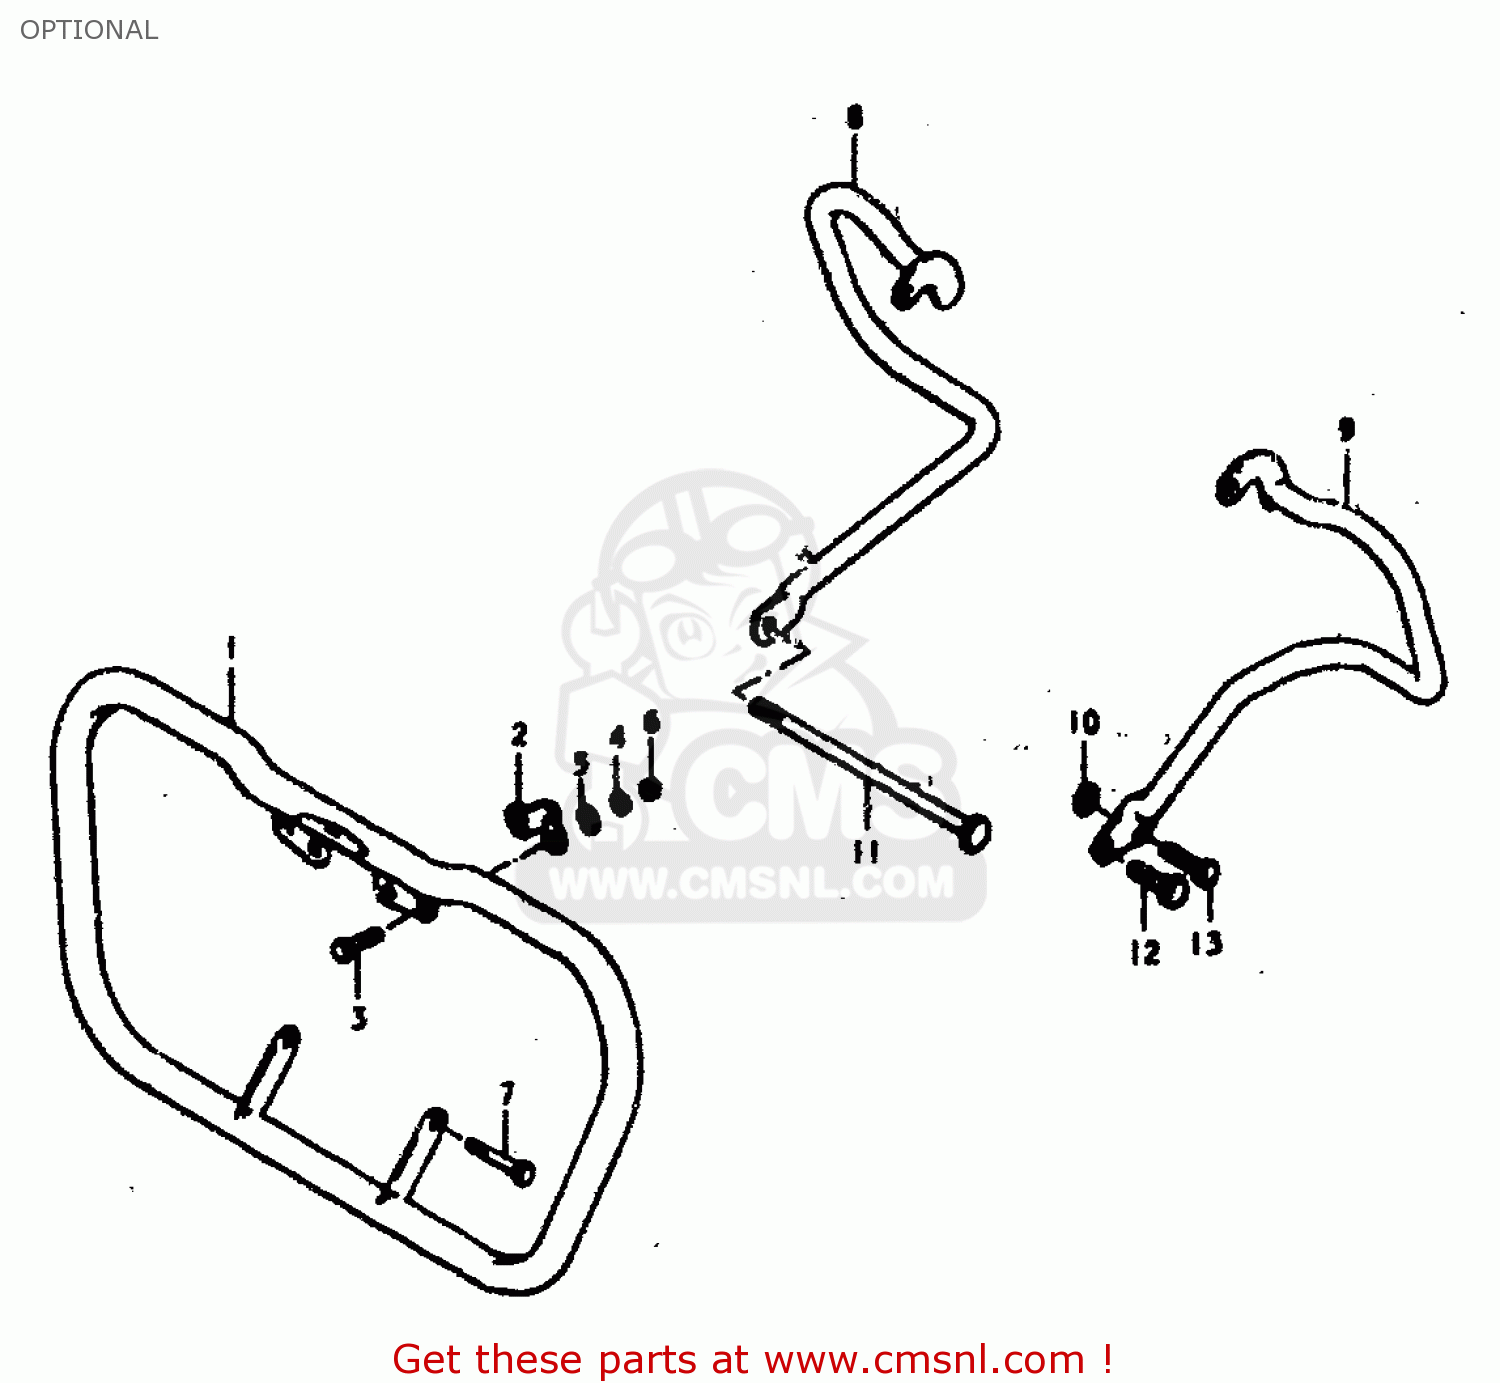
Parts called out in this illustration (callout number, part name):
1	BUMPER,FRONT
2	PLATE, UPPER
3	BOLT
4	LOCK WASHER
5	WASHER
6	NUT
7	BOLT
8	BUMPER,REAR SIDE RH
9	BUMPER,REAR SIDE LH
10	WASHER
11	SHAFT,REAR SWING ARM
12	BOLT(10X45)
13	BOLT 8X45
